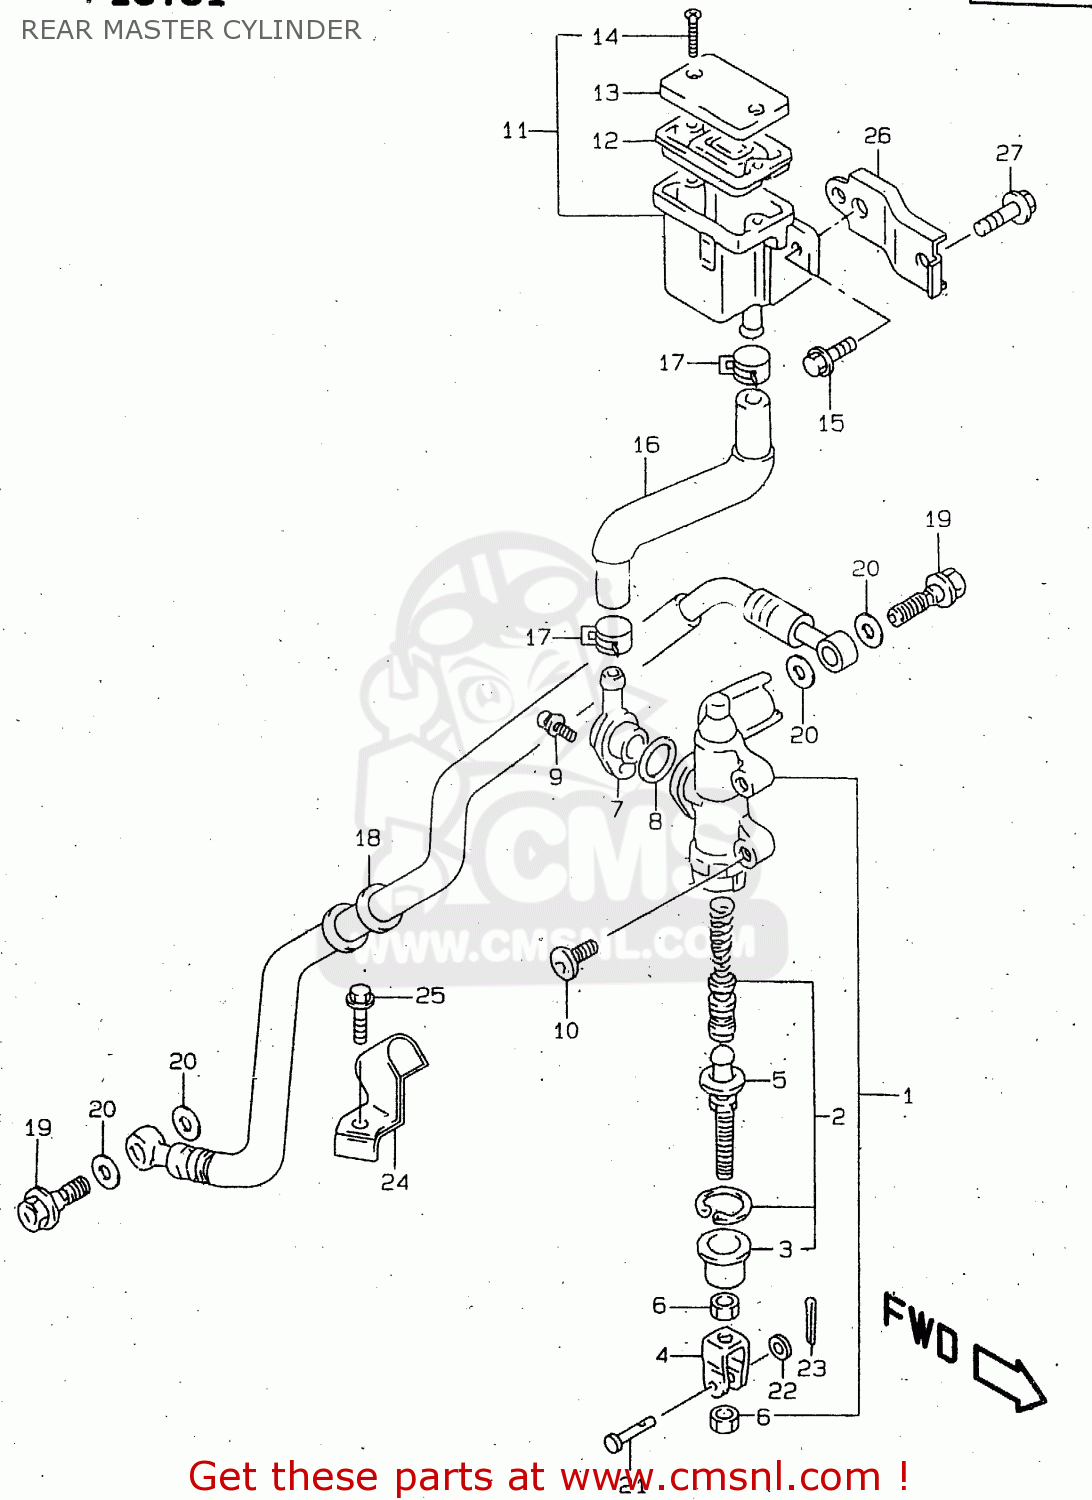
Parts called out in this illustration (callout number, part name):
1	CYLINDER ASSY,RR MASTER
2	PISTON/CUP SET
3	BOOT
4	YOKE
5	ROD,PUSH
6	NUT
7	CONNECTOR
8	O RING
9	SCREW
10	SCREW(6X25)
11	TANK ASSY,RR RESERVOIR
12	DIAPHRAGM
13	CAP
14	SCREW
15	BOLT
16	HOSE,RESERVOIR TANK
17	CLIP
18	HOSE,RR BRAKE
19	BOLT UNION
20	WASHER(10X15X1.5)
21	PIN
22	WASHER
23	PIN
24	CLAMP,RR BRAKE HOSE
25	BOLT
26	BRACKET,RR RESERVOIR TANK
27	BOLT
